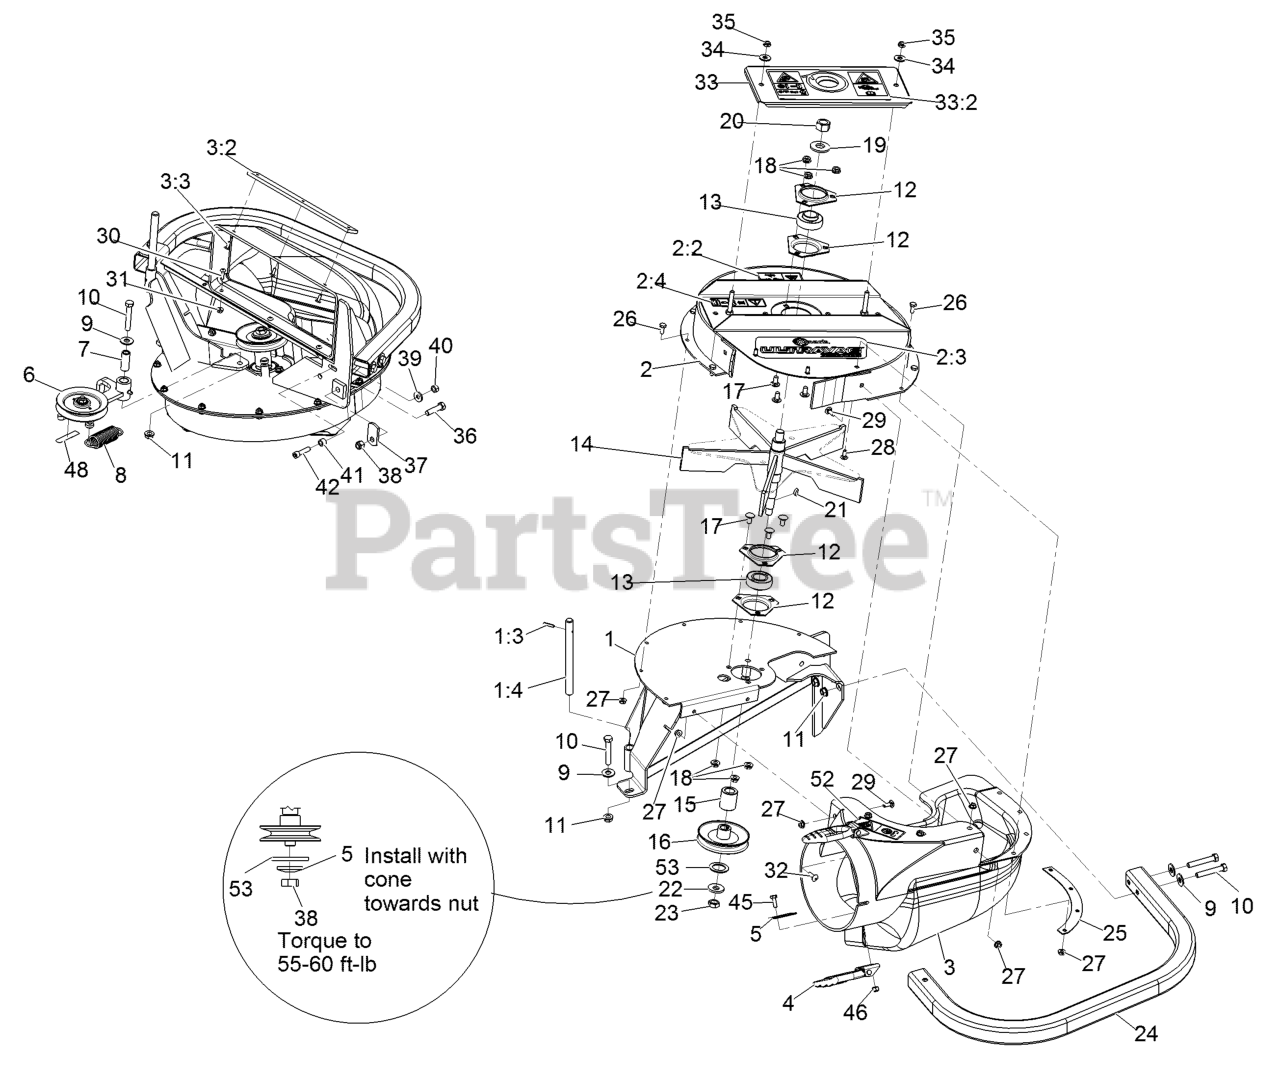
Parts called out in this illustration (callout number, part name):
1	WLD,FRAME LG BLOWER
1:3	PIN-ROLL
1:4	SHAFT-CATCHER, GRASS
2	ASM-UPPER HOUSING LARGE
2:2	DECAL-WARNING, TRACTION
2:3	Decal-Ultravac X-Series
2:4	DECAL-COVER, MISSING
3	ASM,BLOWER CHUTE LZ
3:2	PLATE,REINFORCEMENT LARGE
3:3	RIVET-BLIND
4	LATCH-RUBBER
5	PLATE-BACKING
6	ASM, Idler
7	BUSHING
8	SPRING-IDLER
9	WASHER-FLAT
10	SCREW-HH
11	NUT-HHF, WHIZ
12	HOUSING-FLANGE
13	BEARING
14	IMPELLER
16	SHEAVE
17	SCREW-CARR
19	WASHER-SPRING
20	NUT-HEX
21	KEY-WOODRUFF
22	WASHER-SPRING
23	NUT-JAM
25	PLATE-BACKING, BLOWER
26	SCREW-HH
28	SCREW-CARR
29	BOLT-CARR
30	SCREW-HEAD, TRUSS
33	ASM, BEARING COVER
33	COVER, BEARING
33:2	DECAL-WARNING, BLOWER
34	WASHER-FLAT
35	NUT-LOCK, NI
36	SCREW-HH
37	LATCH-CATCHER, GRASS
38	NUT-LOCK, NI
39	WASHER-SPRING
40	NUT-HEX
41	BUSHING, LOCATOR
42	SCREW-HSH
45	SCREW-HH
46	NUT-LOCK, NI
48	DECAL-WARNING
52	Decal-Blower-Impeller Hazard
53	WASHER-SPACER
